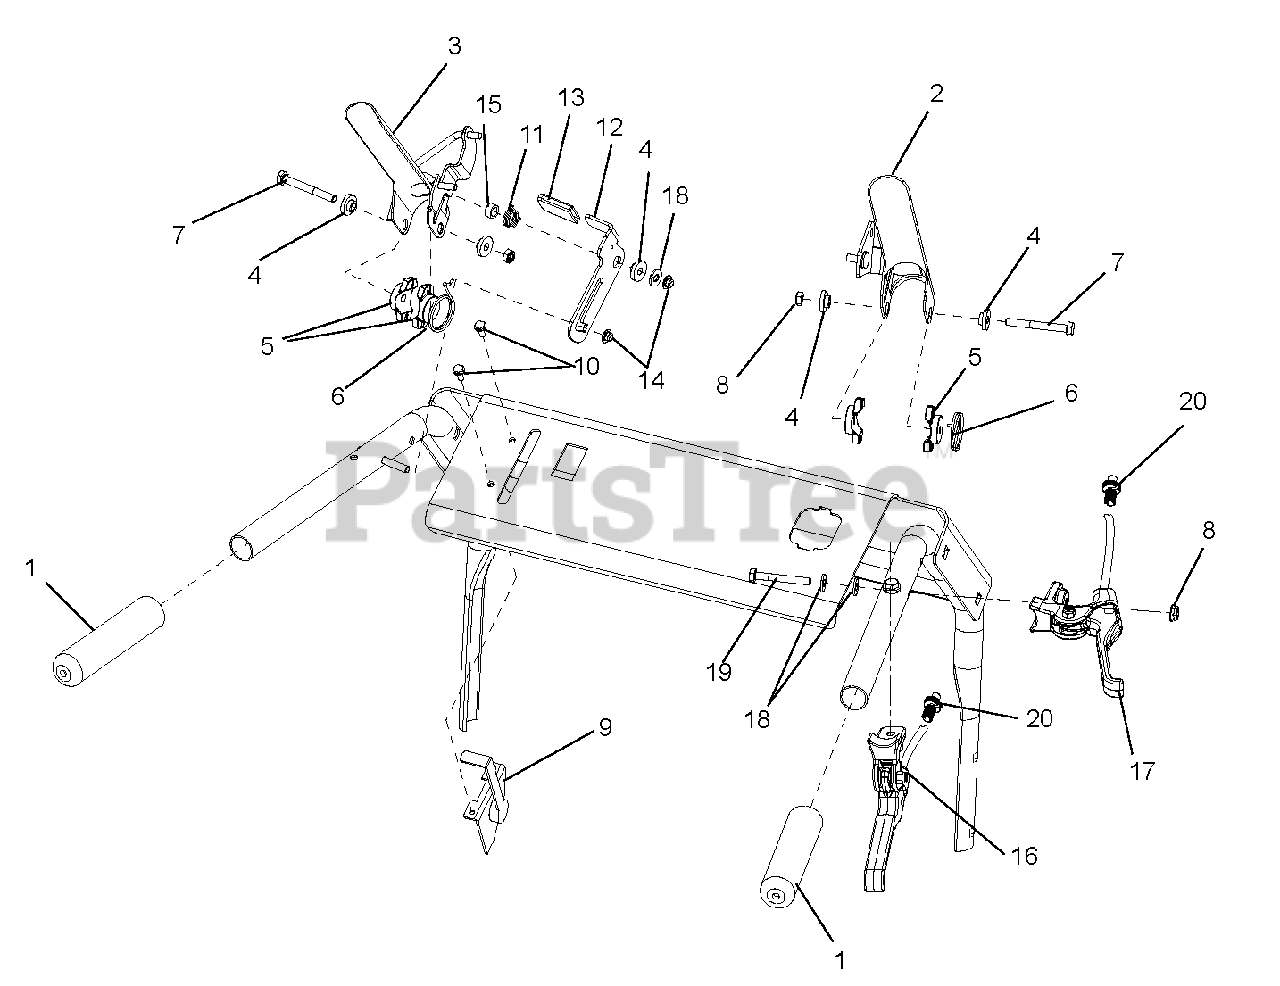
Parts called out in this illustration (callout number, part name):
1	Grip, Handle
2	Paddle, Pillow Brake
3	Weldment, Paddle Left Hand
4	Bushing, Flange .266 x .42 x .150 x .750
5	Spacer, Handlebar
6	Spring, Torsion
7	Bolt, Hex .25-20 x 2.25
8	Nut, Nylon Jam .250-20
9	Cable, Throttle
10	Screw, Tapping 10-24 x .50 Hex Washer Head
11	Spring, Torsion
12	Bracket - Lever, Interlock
13	Grip, Thumb Latch
14	Nut, Push .25
15	Tube, Spacer .33 x .50
16	Lever, Control With Cable Forward
17	Lever, Control With Cable Reverse
18	Washer, Flat Steel .281 x .62 x 0.65
19	Bolt, Hex .25-20 x 2.00
20	Cable Adjuster, Steel (Service Only)
